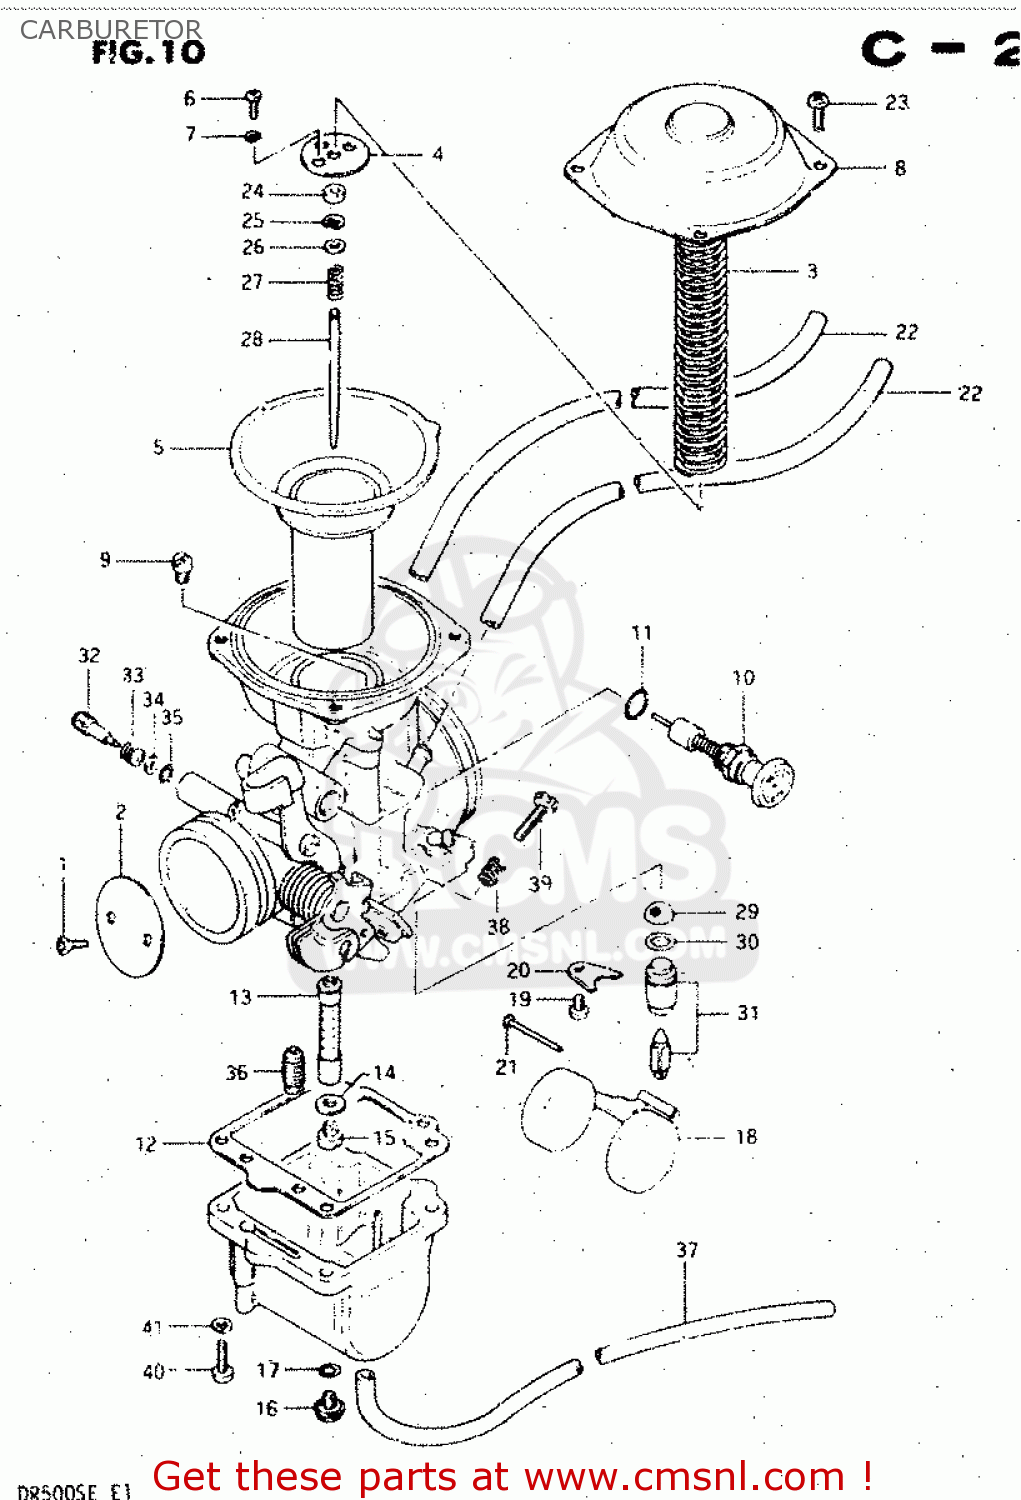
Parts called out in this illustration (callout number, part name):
1	SCREW
2	VALVE,THROTTLE (BUTTERFLY)
3	SPRING,DIAPHRAGM
4	PLATE
5	DIAPHRAGM ASSEMBLY
6	SCREW
7	LOCK WASHER
8	COVER
9	JET
10	VALVE,STARTER
11	O RING
12	GASKET,FLOAT CHAMBER (NAS)
13	JET,NEEDLE
14	WASHER
15	JET,MAIN(125)
16	PLUG,DRAIN
17	GASKET (NAS)
18	FLOAT
19	SCREW 4X6
20	PLATE
21	PIN,FLOAT
22	HOSE
23	SCREW
24	RING
25	CLIP,NEEDLE
26	WASHER
27	SPRING
28	NEEDLE JET
29	FILTER
30	O RING
31	VALVE ASSEMBLY,NEEDLE
32	SCREW,PILOT AIR
33	SPRING
34	GASKET
35	O-RING
36	JET
37	HOSE
38	SPRING
39	SCREW,THROTTLE STOP
40	SCREW
41	LOCK WASHER
